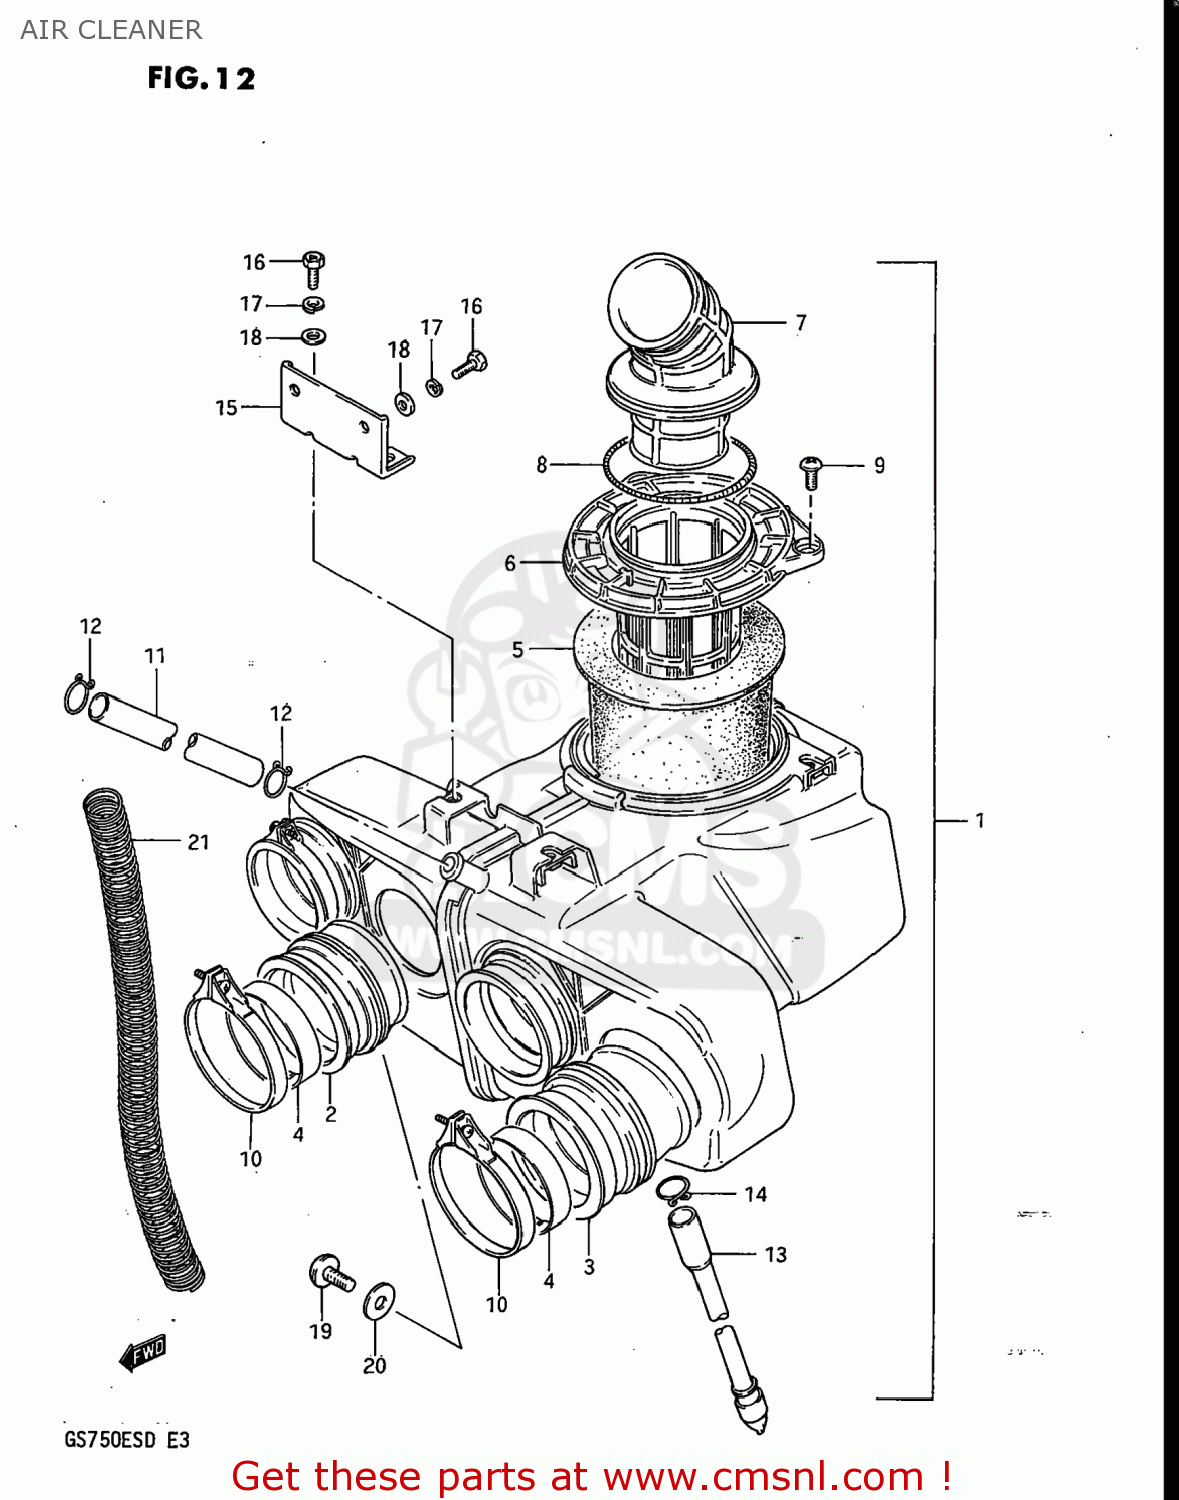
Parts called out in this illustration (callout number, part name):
1	CLEANER ASSEMBLY,AIR
2	TUBE,AIR CLEANER OUTLET
3	TUBE,AIR CLEANER OUTLET
4	RING,CARBURETOR AIR INLET HOSE
5	FILTER,AIR CLEANER
6	HOLDER,AIR FILTER
7	TUBE,AIR CLEANER INLET
8	CLAMP,INLET TUBE AIR CLEANER
9	SCREW
10	CLAMP
11	HOSE
12	CLIP
13	DRAIN TUBE
14	CLIP
15	BRACKET,HOLDER
16	SCREW(6X12)
17	LOCK WASHER
18	WASHER
19	SCREW
20	WASHER
21	SPRING
